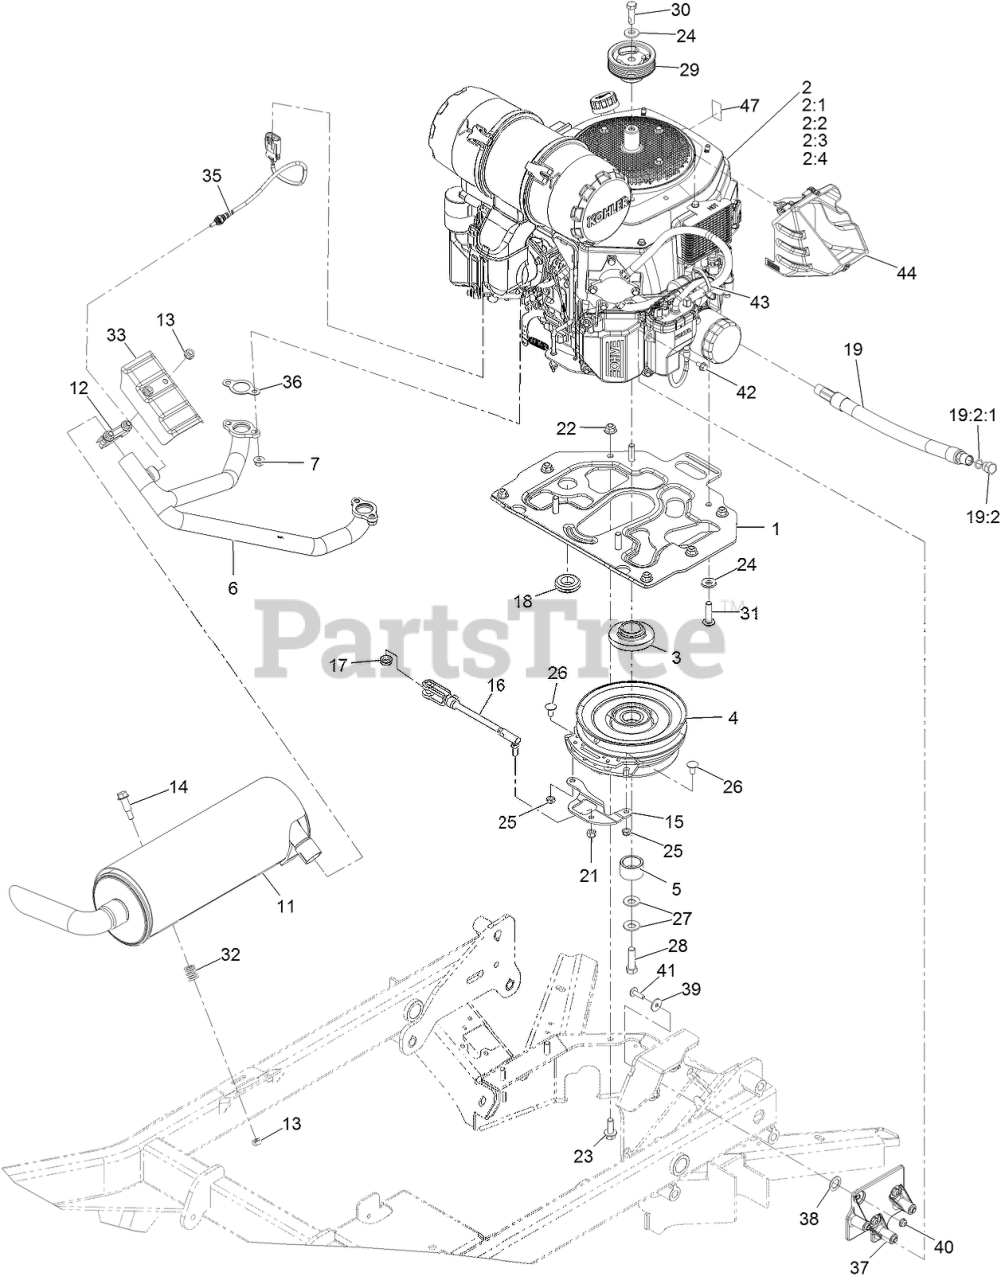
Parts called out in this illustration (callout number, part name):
1	Plate, Engine
2	Engine, Kohler Cv730 EFI
2:1	Kohler 52 050 02-S Engine Oil Filter
2:2	Kohler 25 083 01-S Engine Air Filter
2:3	Kohler 25 083 04-S Safety Filter
2:4	Kohler 25 050 42-S Fuel Filter
3	Spacer, Clutch 1.13
5	Spacer, Clutch
6	Header, Kohler
7	NUT-FLANGE
11	Muffler, 5"
12	CLAMP-MUFFLER
14	Bolt-Shoulder
15	Strap, Clutch
16	ASM, CLUTCH ANCHOR
17	GROMMET
18	GROMMET
19	OIL DRAIN HOSE ASM
19:2	PLUG-HH
19:2:1	O-RING
21	NUT-LOCK
22	NUT-HF, NI
23	SCREW-HHF 3/8-16 X 1
24	WASHER-BELLEVILLE
25	NUT-LOCK, NI
26	SCREW-CARR
27	WASHER-SPRING
28	SCREW-HH 7/16-20 X 1 1/2 W/LOCTITE
29	PULLEY, CRANK
30	Screw-HH, Patch
31	SCREW-BHTF
33	Shield, Heat
35	Sensor, Mini O2
36	GASKET-EXHAUST
37	Bracket-Pump, Fuel
38	Washer-Rubber
41	SCREW-TRUSS
42	SCREW-HHF
44	Duct, Air
47	Decal-10W-50 Oil
